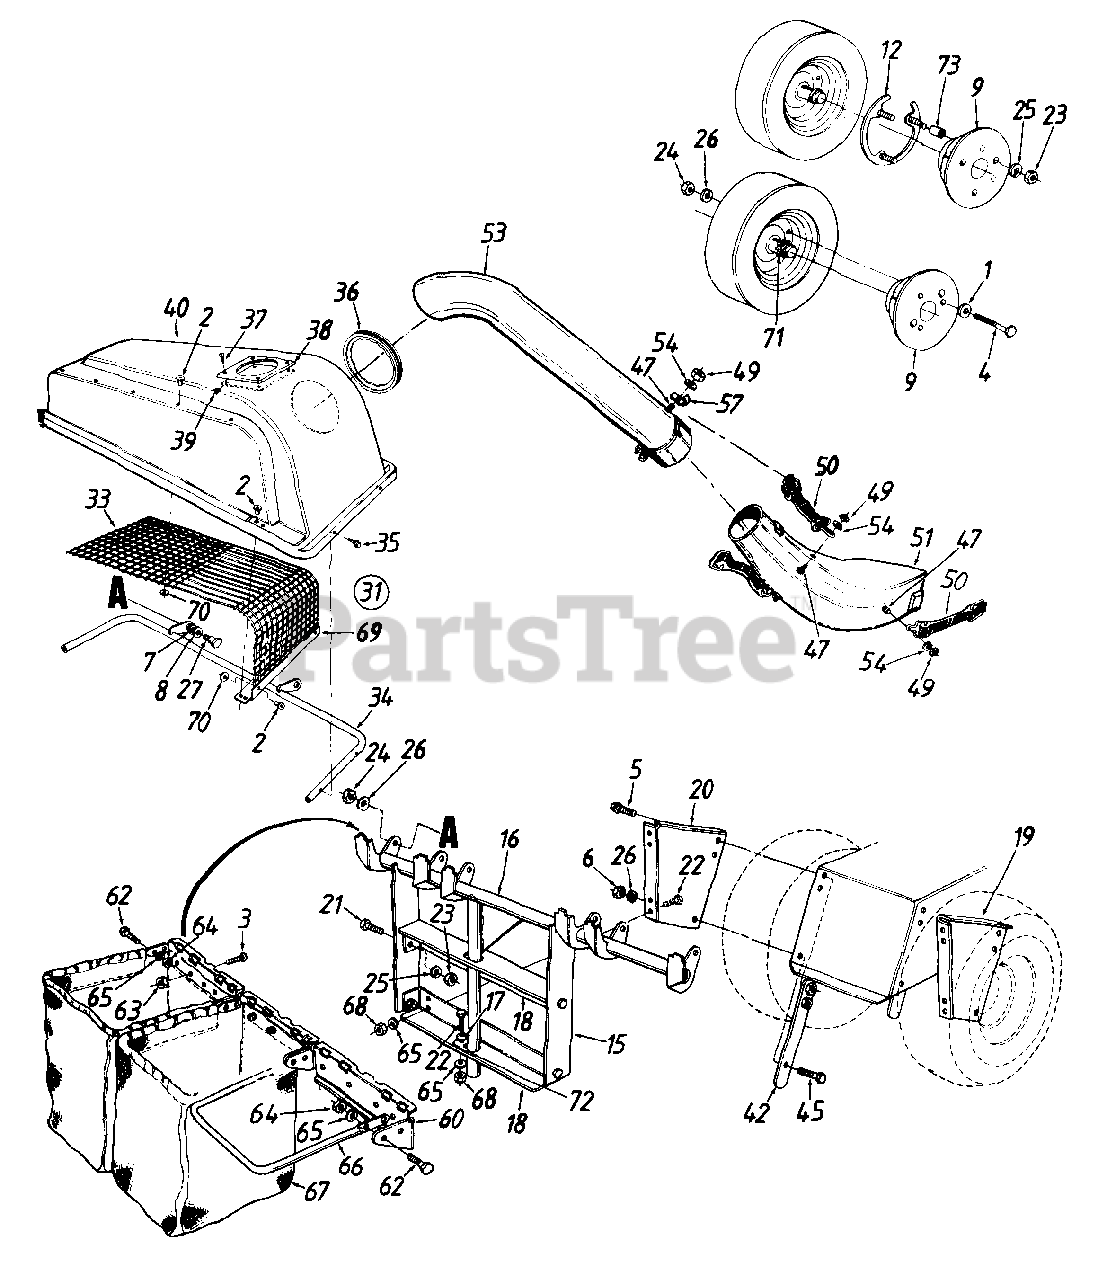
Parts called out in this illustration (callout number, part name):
1	Fl-Wash. .385" I.D.
2	Pop Rivet
3	Truss Mach. Scr. #10-24 x .38" Lg.
4	Hex Bolt 3/8-16 x 4.5" Lg.
5	Hex Wash. Hd. Tap Scr. 5/16-18 x .62"
6	Hex Nut 3/8-24 Thd.
7	Bell-Wash. .515" I.D.
8	Fl-Wash. .510" I.D.
15	Catcher Support Tube Mtg. Brkt.
18	Catcher Latch and Support Brkt.
22	Hex Bolt 1/4-20 x .62" Lg. - Grade 5
23	Hex Nut 5/16-18 Thd.
24	Hex Nut 3/8-16 Thd.
25	L-Wash. 5/16" I.D.
26	L-Wash. 3/8" I.D.
27	Shld. Bolt 3/8-16 x .500" Dia.
31	Grass Catcher Cover Ass'y. Comp.
37	Truss Mach. B-Tap Scr. #10 x .5" Lg.
38	Plastic Plate
39	Speed Nut
40	Grass Catcher Cover
47	Hex Bolt 1/4-20 x .50" Lg.
49	Hex Ins. L-Nut 1/4-20 Thd.
50	Retainer Strap Ass'y.
51	Discharge Chute
53	Catcher Elbow Tube
54	L-Wash. .270" I.D. x .57" O.D.
57	Retainer Hook Brkt.
62	Hex Bolt 1/4-28 x .75" Lg.
63	Hex Sems Nut #10-24 Thd.
64	Hex Nut 1/4-28 Thd.
65	L-Wash. 1/4" I.D.
66	Catcher Bag Frame
67	Grass Catcher Bag
68	Hex Nut 1/4-20 Thd.
71	Foam Strip 1-1/8" x 1-1/2" x 3/8"
